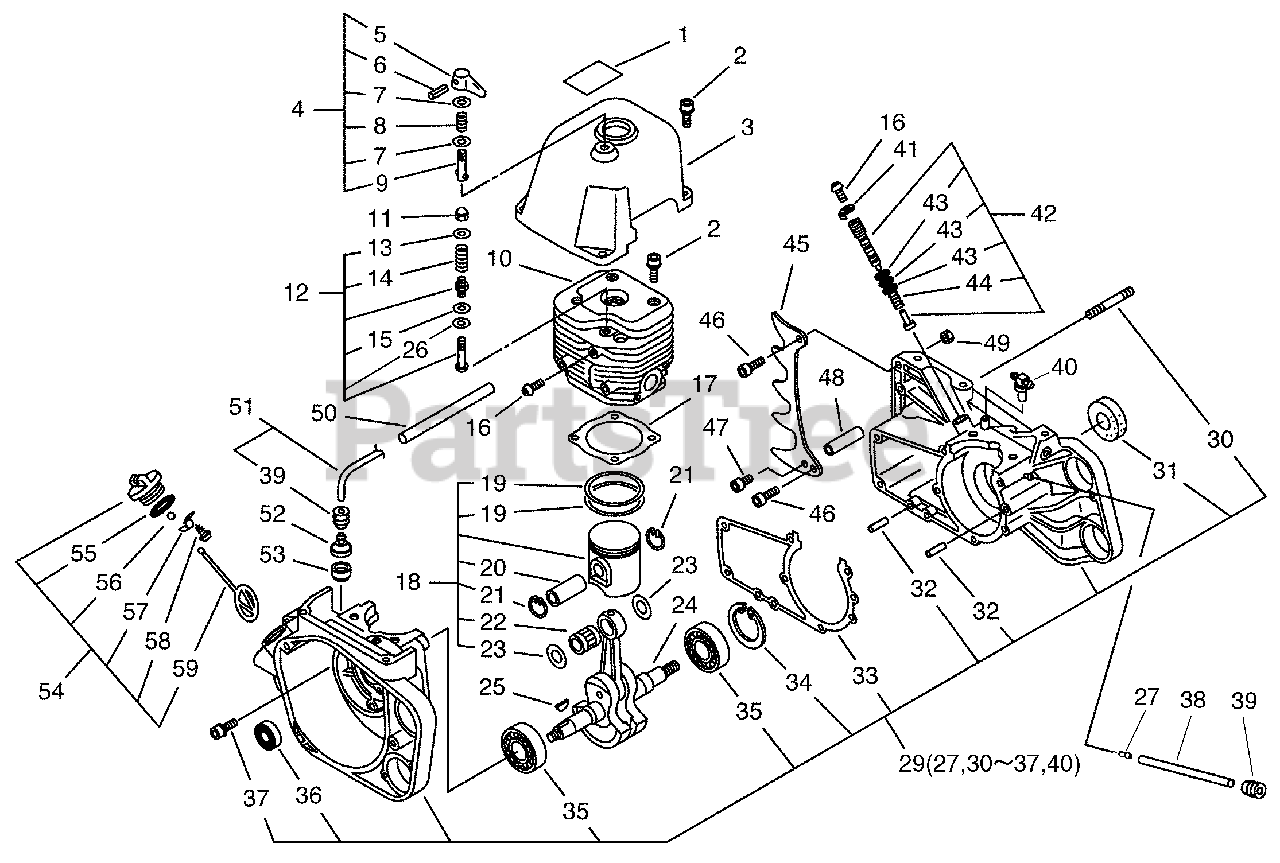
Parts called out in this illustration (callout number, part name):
1	LABEL - DECOMPRESSION
2	SCREW - 6X25
3	COVER, CYLINDER
4	LEVER, DECOMPRESSION
5	LEVER, DECOMPRESSION
6	PIN - SPRING -- 2X14
7	WASHER - 5
9	SHAFT, DECOMPRESSION
10	CYLINDER
11	NUT - 4 -- CAP
12	DECOMPRESSION ASSY
14	SPRING, VALVE
15	GASKET - 2.0
15	GASKET - 1.5
16	SCREW - 5X10
17	GASKET, CYLINDER
18	PISTON KIT
19	RING, PISTON
20	PIN, PISTON
21	RING, RETAINING
22	BEARING, NEEDLE
23	SPACER, PISTON
24	CRANKSHAFT ASSY
26	GASKET - 1.0
27	CONNECTOR
29	CRANKCASE KIT
30	STUD, GUIDE BAR
31	SEAL, OIL
32	PIN - LOCATING
33	GASKET, CRANKCASE
34	RING, RETAINING - 47
35	BEARING, BALL - 6204
36	SEAL, OIL
37	SCREW - 6X30
38	PIPE - IMPULSE
40	CONNECTOR KIT
41	LOCKWASHER
42	AUTO-OILER ASSY
43	O-RING - 5
46	SCREW - 6X20
47	SCREW - 5X14
48	CATCHER, CHAIN
49	LOCKNUT - 6
50	TUBE, PROTECTIVE
52	FILTER, OIL
53	COVER, OIL FILTER
54	CAP ASSY
55	O-RING - 25
56	VALVE, BALL
57	RETAINER
58	SCREW - 3X8
59	CONNECTOR, CAP
